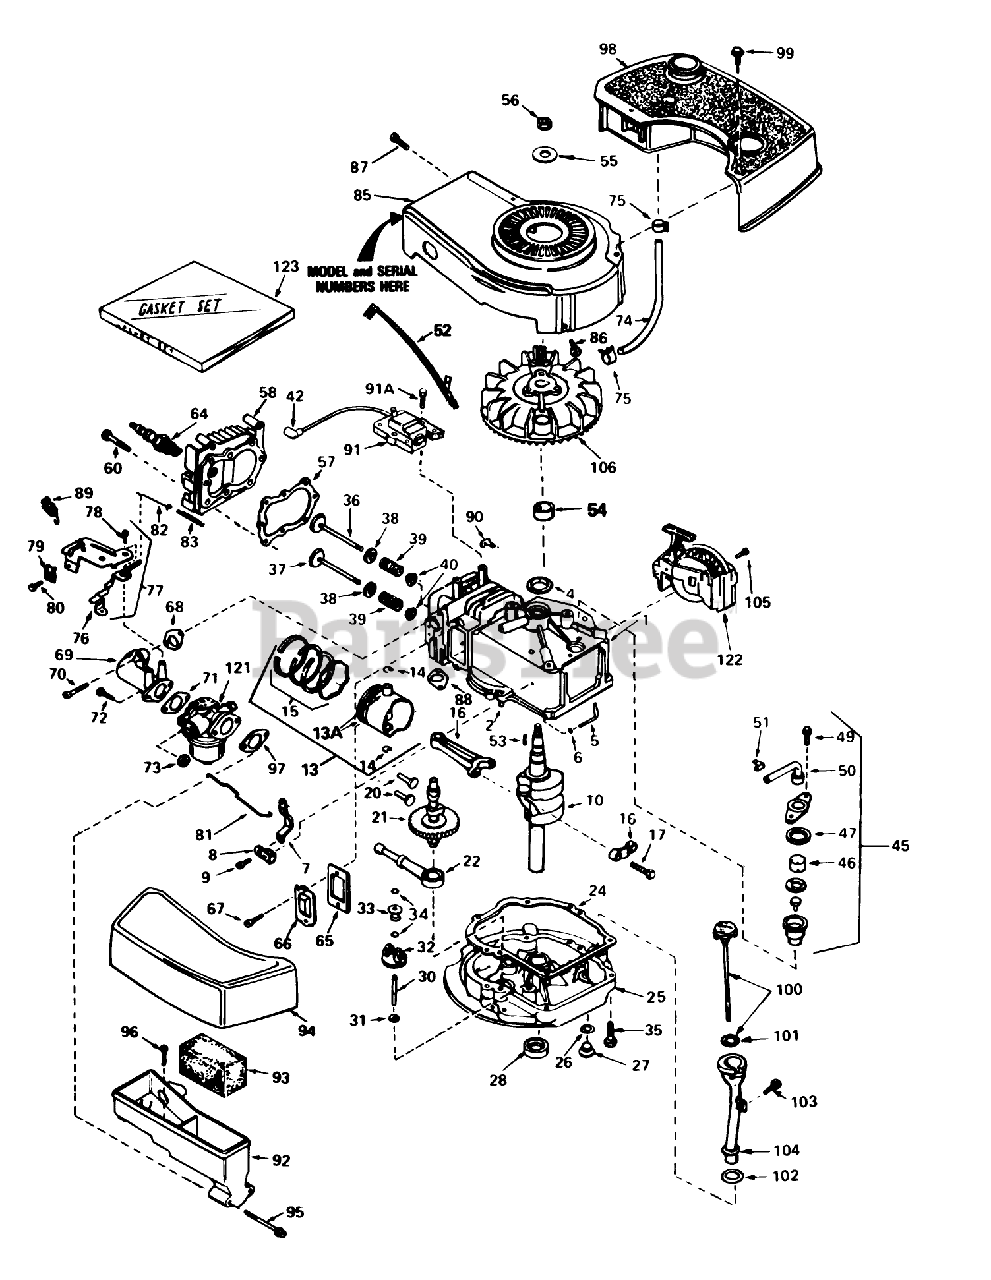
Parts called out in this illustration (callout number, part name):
1	Cyiinder Assy. (Incl. Ref. #2, 4 105)
2	Pin-Dowel
4	Seal-Oil
5	Rod, Governor (Incl. No. 36)
6	Washer-Flat
7	Governor Lever
8	Clamp-Lever, Governor
9	Screw
10	Crankshaft
13	Piston, Pin Ring Assy. (Std.) (Incl. Ref. #13A, 14 15)
13	Piston, Pin Ring Assy. (.010 oversize) (Incl. Ref. #13A, 14 15)
13	Piston, Pin Ring Assy. (.020 oversize) (Incl. Ref. #13A, 14 15)
13A	Piston Pin Assy. (Incl . Ref. . #14) (Std.)
13A	Piston Pin Assy. (Incl. Ref. #14) (.010 Oversize)
13A	Piston Pin Assy. (.020 oversize) (Incl. Ref. #14)
14	Ring-Retaining, Piston Pin
15	Ring Set (Std.)
15	Ring Set (.020" OS)
15	Ring Set (.010" OS)
16	Rod Assy., Connecting (Incl. Ref. #17)
17	Bolt-Rod, Connecting
20	Lifter-Valve
21	Camshaft(Mech.Comp. Release)
22	Oil Pump ASM
24	Gasket, Mounting
25	Flange Assy., Mounting (Incl. Ref. #26thru 30)
26	Gasket-Oil Drain
27	Plug Oil Drain
28	Seal Oil
30	Shaft-Governor
31	Washer-Flat
32	Governor Gear ASM
33	Spool-Governor
34	Ring-Retaining
35	Screw (1/4-20 x 1-1/4)
36	Valve, Intake (Std.) (Incl. Ref. #40)
36	Valve, Intake (1/32" oversize)(Incl. No. 40)
37	Valve, Exhaust (Std.)(Incl. No. 40)
37	Valve, Intake (1/32" oversize)(Incl. No. 40)
38	Cap-Upper Valve Spring
39	Spring-Valve
40	Cap-Valve, Spring
42	Cover-Spark Plug
45	Breather Assy. (Incl. Ref. #46 thru 51)
46	Element-Breather
47	Gasket-Breather
49	Screw (10-24 x 9/16)
50	Tube, Breaker
51	Clip, Breather
52	Wire-Ground
53	Key-Flywheel
54	Spacer
55	Washer-Belleville
56	Nut-Flywheel
57	63573 GIL 42 SNWTHW
58	Head-Cylinder
60	Screw (5/16-18x1-1/2)
64	Plug, Spark (J17LM or equiv.)
64	Plug, Spark (Champion RCJ-8)
65	Gasket-Breather
66	Cover-Valve
67	Screw
68	Gasket-Intake
69	Pipe, Intake (Incl. No. 68)
70	Screw (1/4-20 x 1)
71	Gasket-Carburetor
73	Nut and Lock Washer (1/4-28)
74	Line-Fuel
75	Clamp-Line, Fuel
76	Lever Control
77	Control Assy., Speed (Incl. Nos, 76, 78 89)
78	Screw, Hex Washer Hd Shoulder Self-Tap
79	Conduit
80	Screw (10-32 x 3/8)
81	Link-Throttle
82	Link Governor Spring
83	Spring Governor
85	Housing-Blower
86	Screw (1/4-20x19/32)
87	Screw (10-24 x 9/16)
88	Gasket Exhaust
89	Terminal
90	Clip-Wire
91	Solid State
91A	Screw
92	Body Air Cleaner
93	Filer, Air
94	Cove, Air Cleaner
95	Screw Fil Hd.
96	Screw, Hex Hd.
97	Gasket-Air Cleaner
98	Tank-Fuel
99	Screw (10-32 x 35/64)
100	Dipstick, Oil (Incl. Ref. #101)(Twist Lock)
101	O-Ring
102	Gasket
103	Screw (10-32 x 1/2)
104	Tube-Oil Fill
105	Screw (1/2-20x5/8)
106	Flywheel
121	Carburetor (Incl. Ref. #71)
122	Starter-Sidemount
123	Gasket Set
